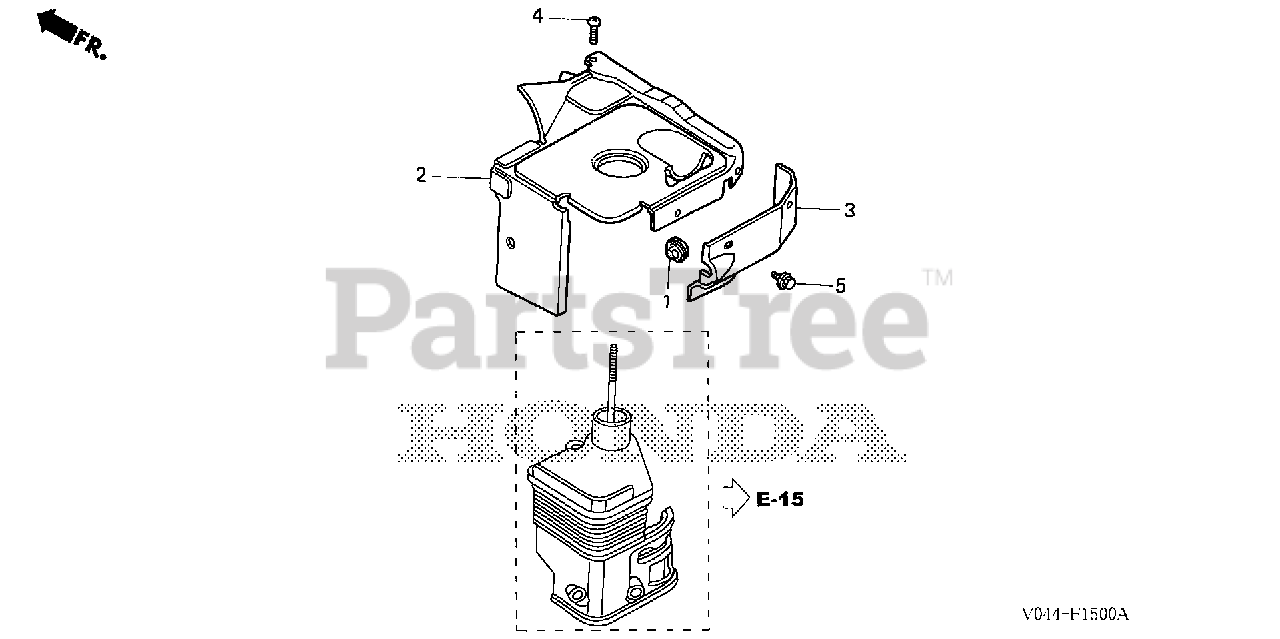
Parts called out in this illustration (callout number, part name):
1	GROMMET, OIL PIPE HOLDER
2	COVER, CONTROL
3	COVER, AIR IN.
4	SCREW, PAN (6X8) (SOURCE: VINTAGE PARTS INC.)
5	BOLT, FLANGE (6X8)
